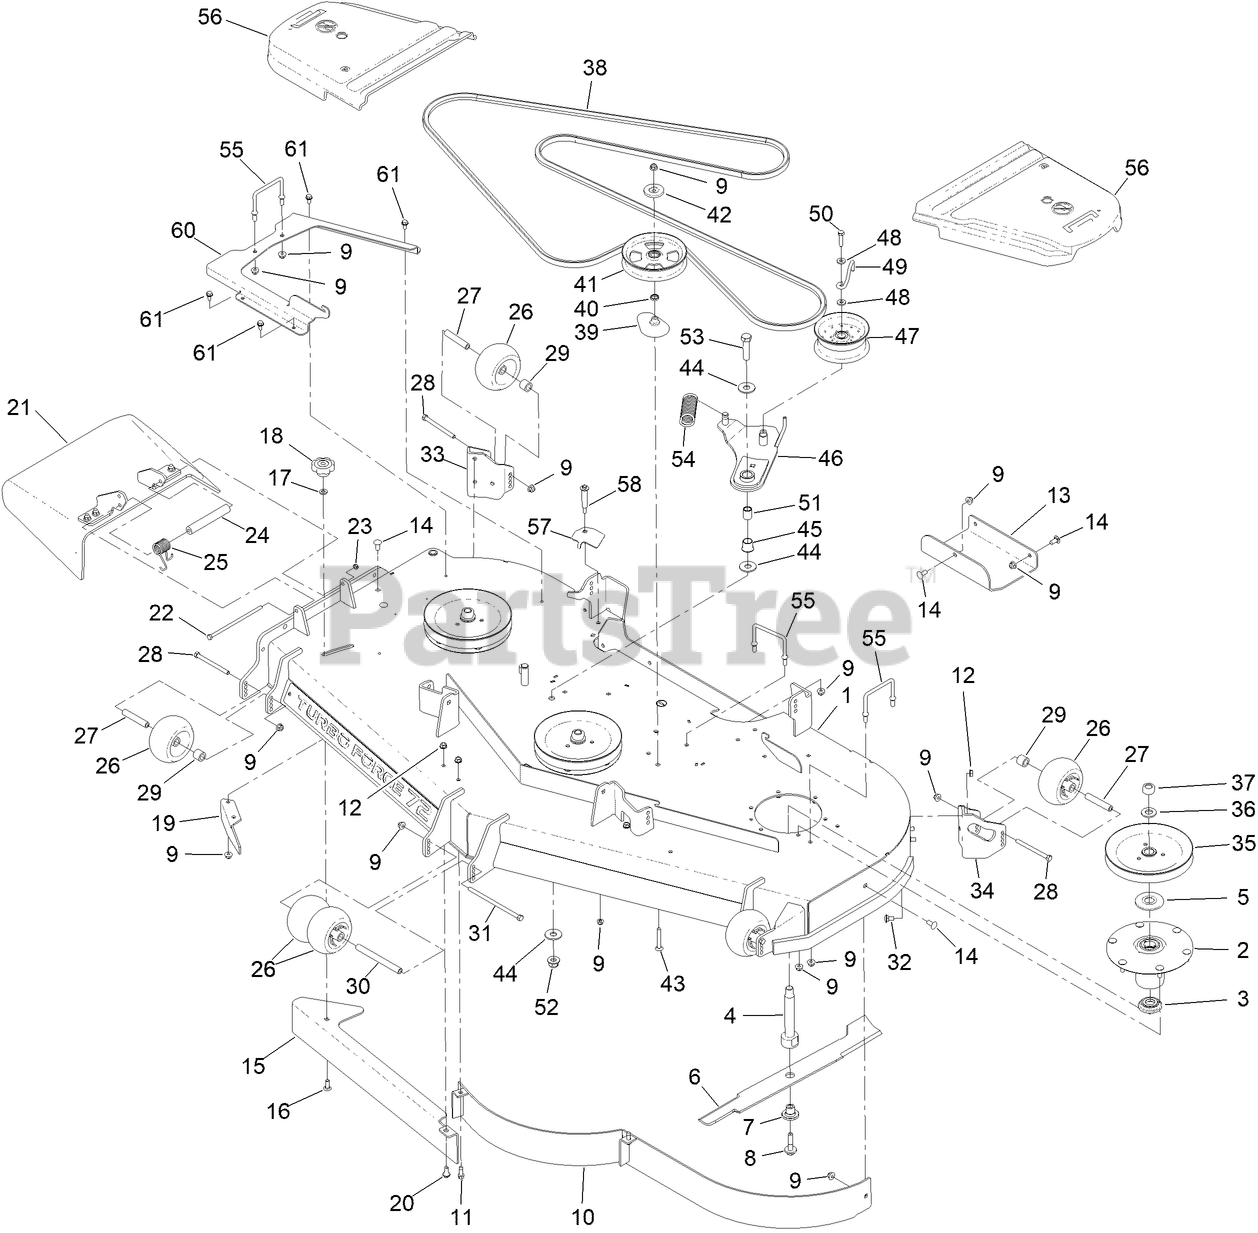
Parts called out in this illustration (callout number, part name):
1	72 DECK ASM W/DECALS
2	SPINDLE ASM
3	GUARD-BOTTOM
4	SHAFT-SPINDLE
5	GUARD-BEARING, TOP
7	BUSHING-HEX
8	SCREW-SEMS
9	NUT-HF, NI
12	NUT-HHF, WHIZ
13	PLATE, SKID 72
14	SCREW-CARR
15	PLATE-BAFFLE
16	SCREW-CARR
17	WASHER-HARDENED
19	BAFFLE-DISCHARGE
20	BOLT-SHOULDER
21	RUBBER DEFLECTOR ASM
22	SCREW-HH
23	NUT-LOCK, NI
24	SPACER
25	SPRING-TORSION
26	ROLLER-SCALP, ANTI
27	TUBE-SPANNER
28	SCREW-HH
29	TUBE-SPACER
30	SPACER-WHEEL
31	SCREW-HH
32	SCREW-CARR
33	MOUNT-WHEEL, RH
34	MOUNT-WHEEL, LH
35	SHEAVE-DRIVE, BLADE
36	WASHER
37	NUT-HEX
38	BELT 5V-72" DECK
39	SPACER-PULLEY
40	SPACER-PLATE, BBC
41	PULLEY-IDLER, FLAT
42	SHIELD-DUST
43	SCREW-CARR
44	WASHER-HARDENED
45	BUSHING, IGUS
46	IDLER ARM ASM [BLACK]
47	IDLER-PULLEY, FLAT
48	SPACER-HUB, BLOWER
49	WIREFORM BELT GUIDE,IDLER, TOP
50	SCREW-HH
51	BUSHING-IDLER PIVOT
52	NUT-HF
53	SCREW-HH
54	SPRING-EXTENSION
55	WIREFORM-COVER
56	COVER-BELT, LH
57	PLATE, BELT-GUIDE
58	BOLT-SHOULDER
60	PLATFORM, BELT COVER 72
61	SCREW-HWHTF
